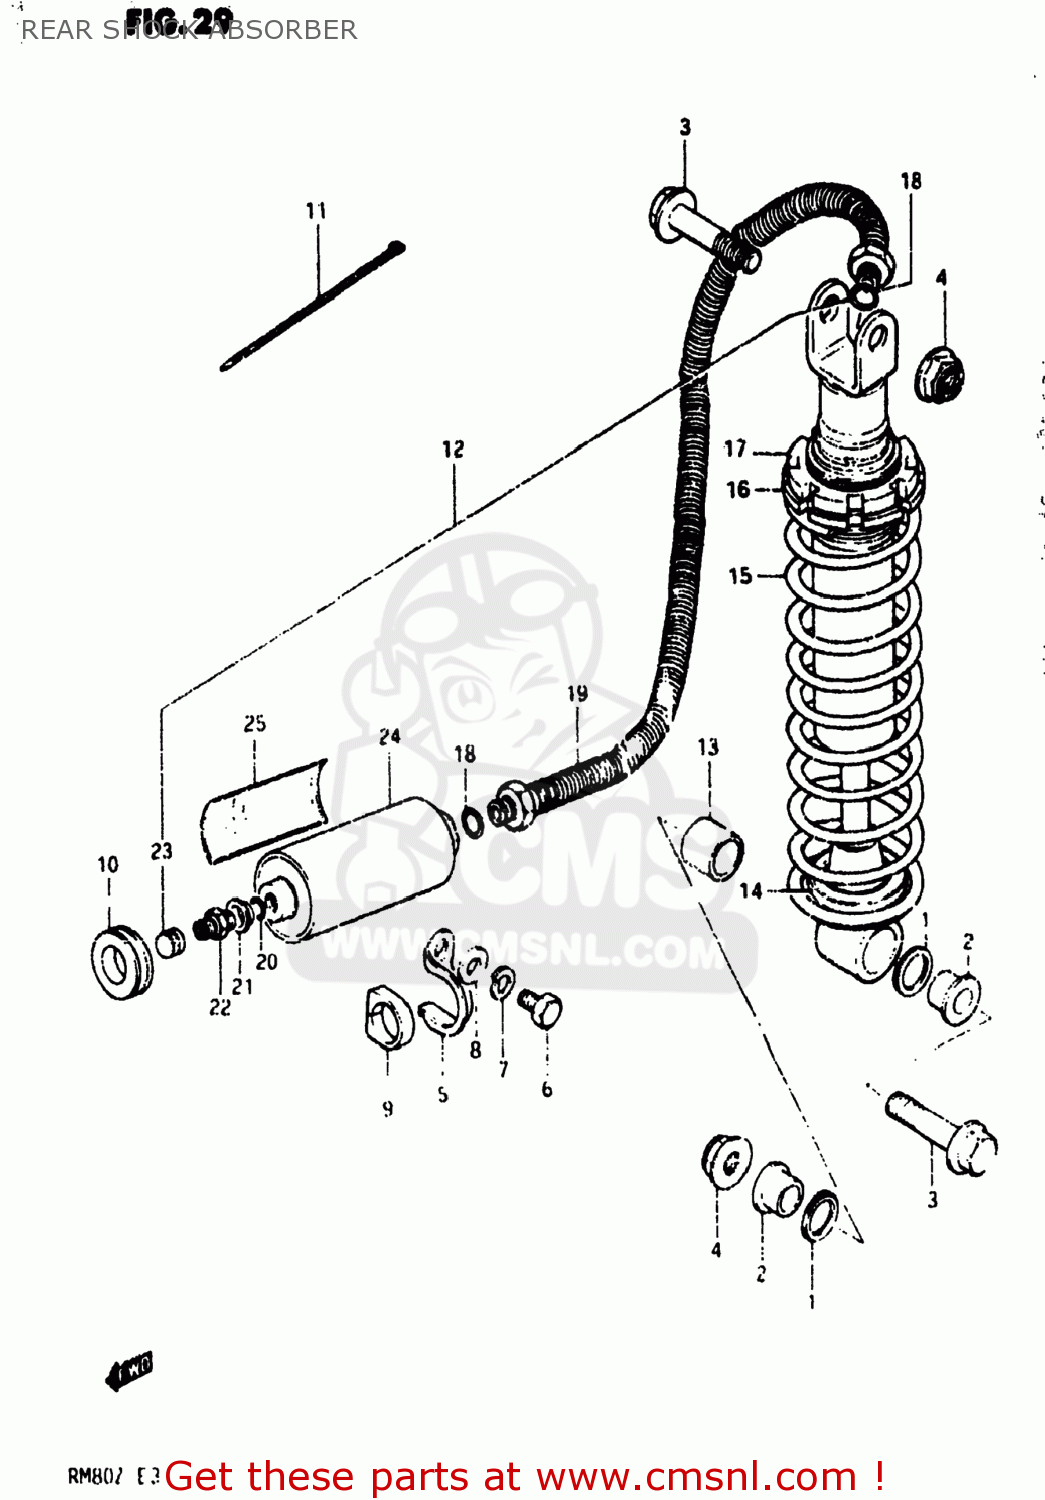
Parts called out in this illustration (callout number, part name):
1	DUST SEAL,LEVER CUSHION UNIT
2	SPACER,LEVER CUSHION UNIT
3	BOLT(10X50)
4	NUT
5	BRACKET, RESERVER TANK
6	BOLT
7	LOCK WASHER
8	WASHER
9	CUSHION,REAR SHOCK ABSORBER TANK
10	CUSHION, FRONT
11	CLAMP
12	ABSORBER ASSEMBLY,REAR SHOCK
13	BUSH,LEVER CUSHION UNIT
14	SEAT, SPRING
15	SPRING
16	ADJUSTER,SPRING
17	NUT,SPRING ADJUSTER
18	O-RING
19	HOSE,REAR SHOCK ABSORBER
20	O-RING
21	WASHER
22	VALVE,FRONT FORK AIR
23	CAP,FRONT FORK AIR VALVE
24	RESERVE TANK,REAR SHOCK
25	LABEL
